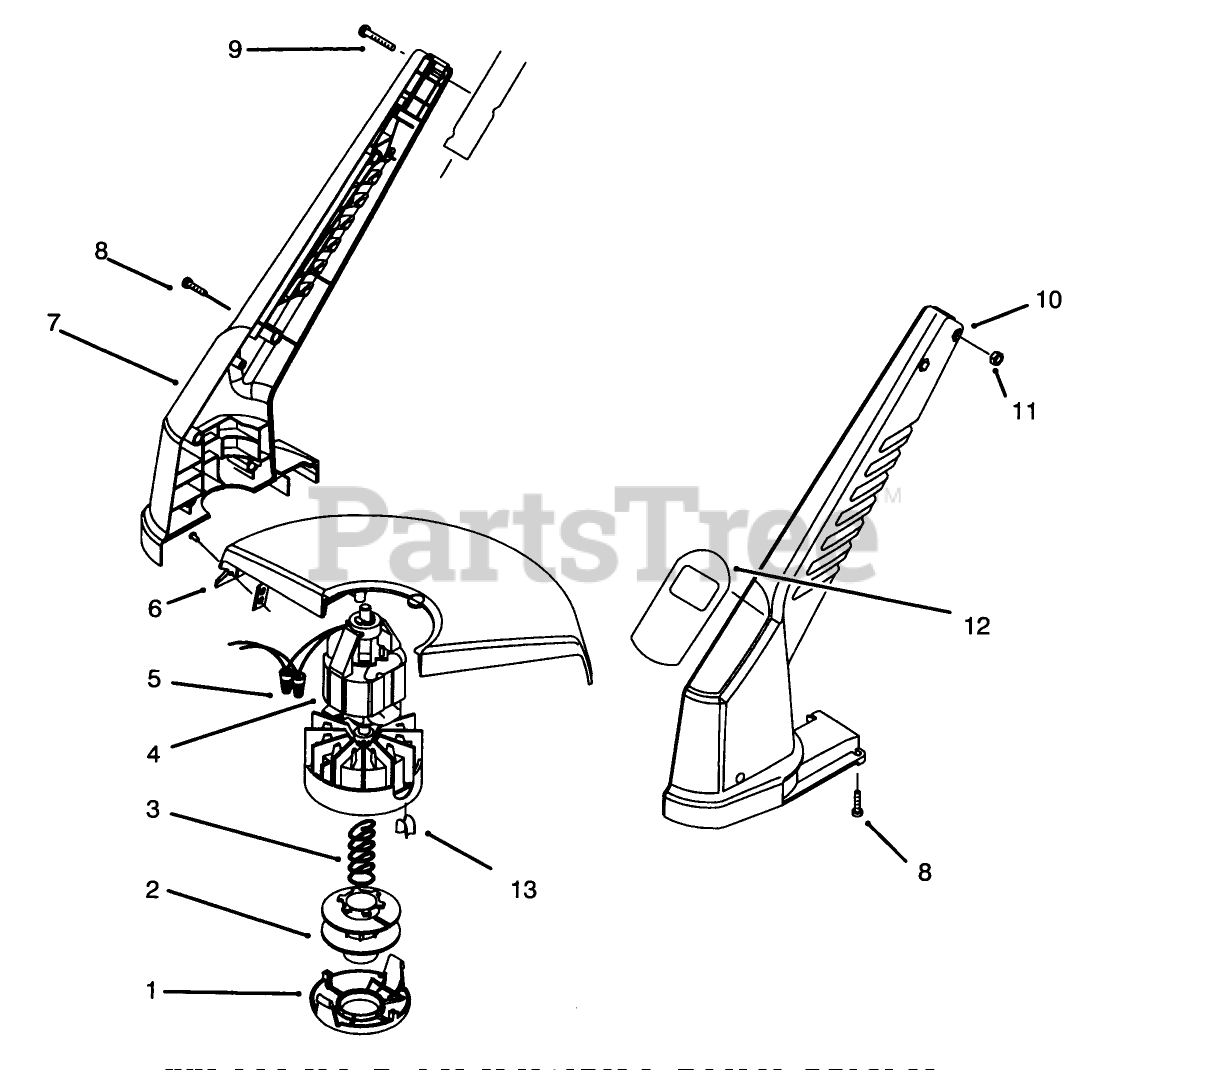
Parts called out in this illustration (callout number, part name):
2	SPOOL-LARGE
3	SPRING-COMPRESSION
4	Motor Assembly (Incl. Ref. #13)
5	CONNECTOR-NUT, WIRE
6	SHIELD ASM - SERVICE
7	RH HOUSING
8	Screw
9	SCREW-PPH
10	LH HOUSING
11	NUT-HEX
12	DECAL - 14" TRIMMER
13	EYELET
